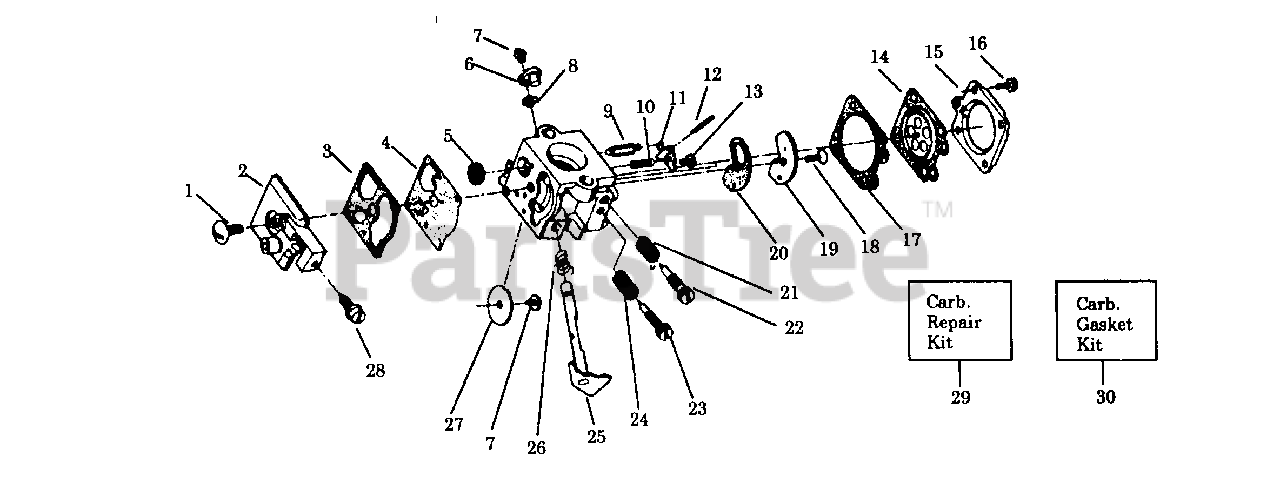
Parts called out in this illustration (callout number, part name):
1	Pump Cover Screw
2	Pump Cover Ass'y. (Inc. #28)
3	Pump Gasket
4	Diaphragm Pump
5	Inlet Screen
6	Swivel Lever Ass'y.
7	Throttle Valve Screw
8	Throttle Shaft Clip
9	Inlet Needle Valve
10	Metering Lever Spring
11	Metering Lever
12	Metering Lever Pin
13	Metering Lever Pin Screw
14	Diaphragm Ass'y. Metering
15	Metering Diaphragm Cover
16	Metering Cover & Throttle Shaft Clip Screw
17	Metering Diaphragm Gasket
18	Circuit Plate Screw
19	Circuit Plate
20	Circuit Plate Gasket
21	Hi Speed Needle Spring
22	Hi Speed Needle
23	Idle Needle
24	Idle Needle Spring
25	Throttle Shaft Ass'y.
26	Throttle Return Spring
27	Throttle Valve
28	Idle Adjustment Screw
29	Kwik Repair Kit
30	Gasket/Diaphragm Kit
